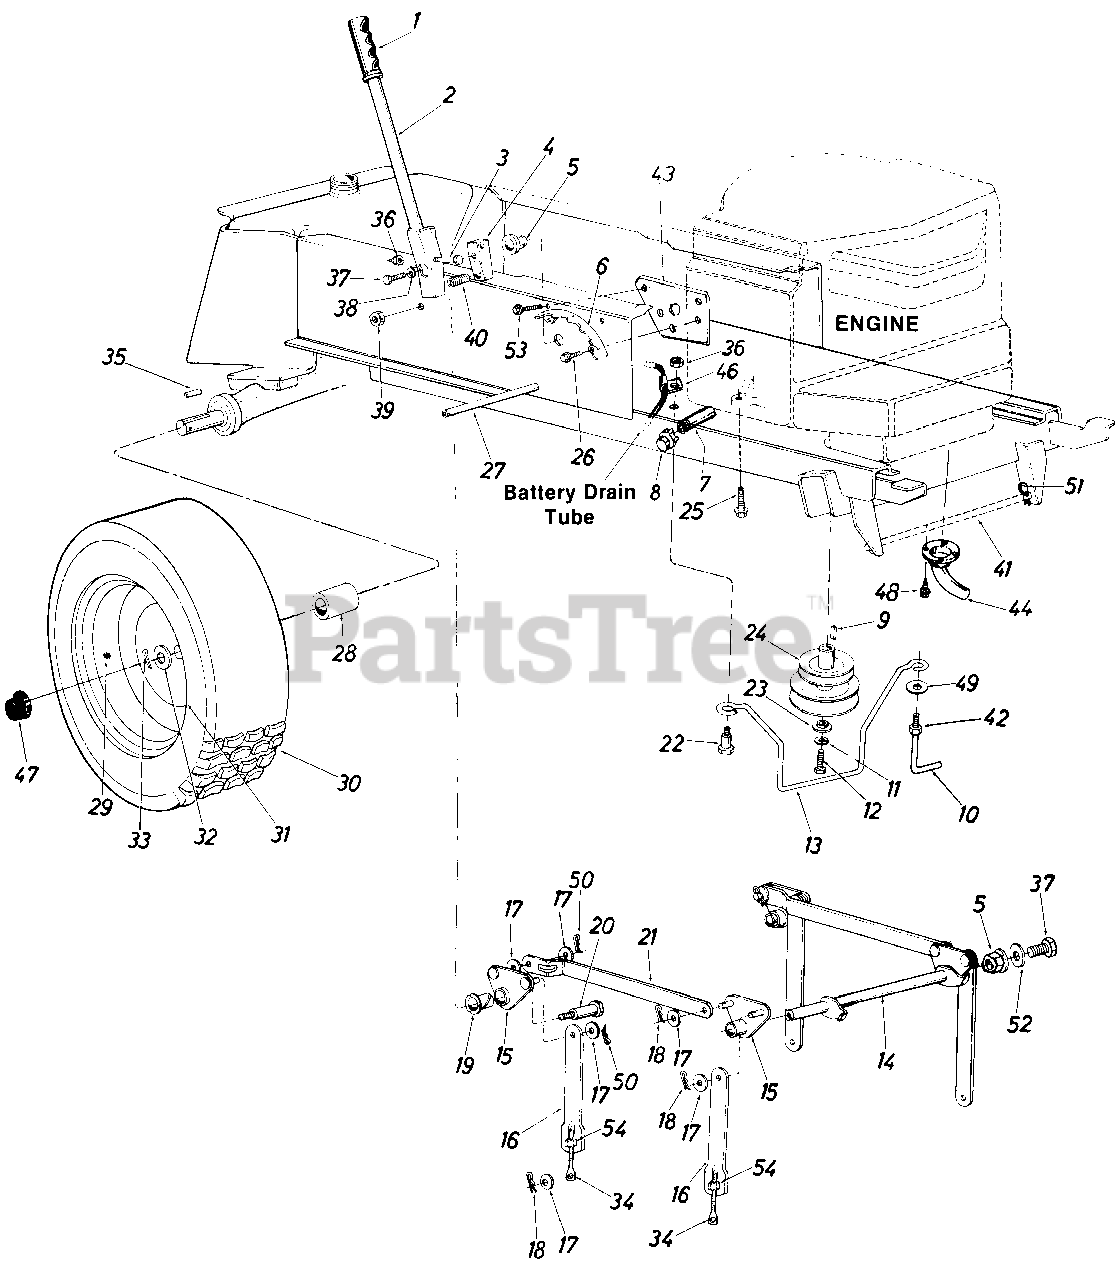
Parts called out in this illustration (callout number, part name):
1	Grip
2	Lift Handle Ass'y.
3	Hex Scr. 5/16-18 x 1.50" Lg.
4	Lift Shaft Drive
5	Plastic Hex Brg. 5/8" I.D.
8	Pipe Cap 3/8-18 Npt.
9	Sq. Key 1/4" x 1/4" x 1.50" Lg.
10	Belt Guard Lock Pin
11	L-Wash. 7/16" Scr.
12	Hex Scr. 7/16-20 x 1.50" Lg.
13	Belt Guard
14	Lift Shaft Ass'y.
15	Lift Pivot Brk't. Ass'y.
16	Adj. Deck Lift Link
17	Fl-Wash. 112" I.D. x 1.00" O.D. x .090
18	Hairpin Cotter
19	Nyliner 5/8" I.D. x .88" Lg.
20	Shld. Scr. 5/8" Dia. x .96" Lg. 3/8-16
23	Flat Wash. .44" I.D. x 1.25" O.D. x .17
24	Two-Step Engine Pulley 4.75" & 5.56
25	Hex Wash. Hd. Scr. 3/8-16 x 1.25" Lg.
26	Hex Thd. Rolling Scr. 5/16-24 x .50" Lg.
27	Running Board Rod
28	Spacer 1.0" I.D. x 1.25" O.D. x 2.12" Lg.
29	Air Valve
33	Cotter Pin 3/16" Dia. x 1.50" Lg.
34	Eye Bolt Adj. Link 1/2-13 Thd.
35	Sq. Key 1/4 x 3.0"
36	Hex Cent. L-Nut 5/16-18 Thd.
37	Hex Scr. 5/16-24 x .62" Lg.
38	L-Wash. 5/16" Scr.
39	Hex Top L-Nut 3/8-16 Thd.
40	Compression Spring
41	Deck Connecting Rod
42	Hex Nut 5/16-24 Thd.
46	Mounting Clamp
47	Hub Cap
48	Hex Wash. Hd. AB-Tap Scr. #10 x .50" Lg.
49	Belle-Wash. .39" I.D.
50	Cotter Pin .09 Dia. x 1.0" Lg.
51	Int. Cotter Pin
52	Flat Wash. .34" I.D. x 1.12" O.D. x .125
53	Hex Wash. Hd. AB-Tap Scr. 5/16 x .62" Lg.
54	Hex Nut 1/2-13 Thd.
